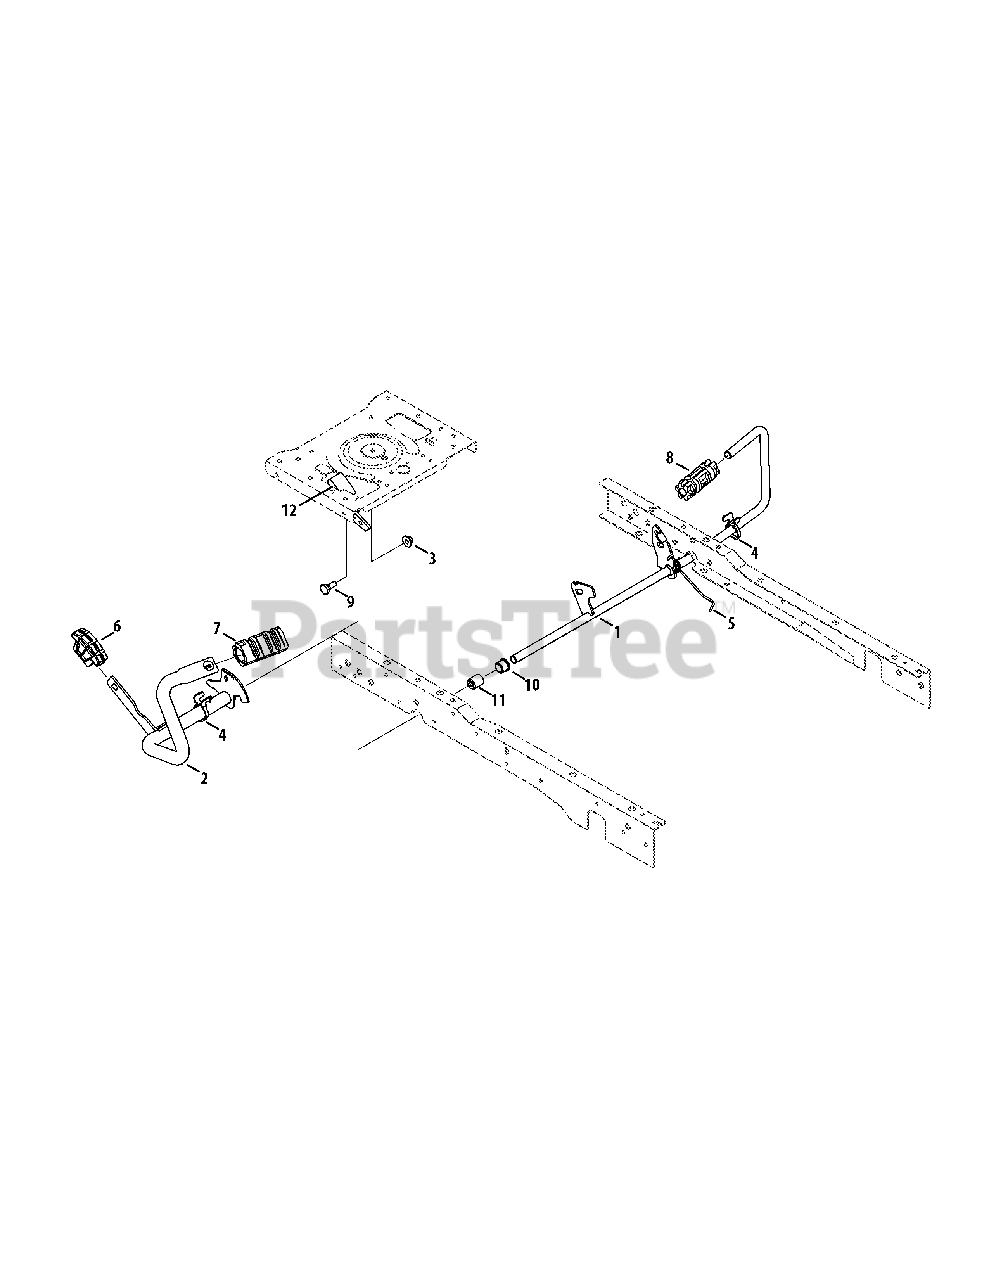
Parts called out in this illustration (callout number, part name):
1	Brake Pedal Assembly
2	FWD/REV Pedal Assembly
3	Flange Lock Nut, 3/8-16
5	Torsion Spring, .725 ID
6	Reverse Pedal Pad
7	Forward Pedal Pad
8	Brake Pedal Pad
9	Shoulder Screw, .50 x .27, 3/8-16
10	Flange Bearing, .63 x .84 x .71
11	Plastic Sleeve Bearing
12	Cruise Latch
